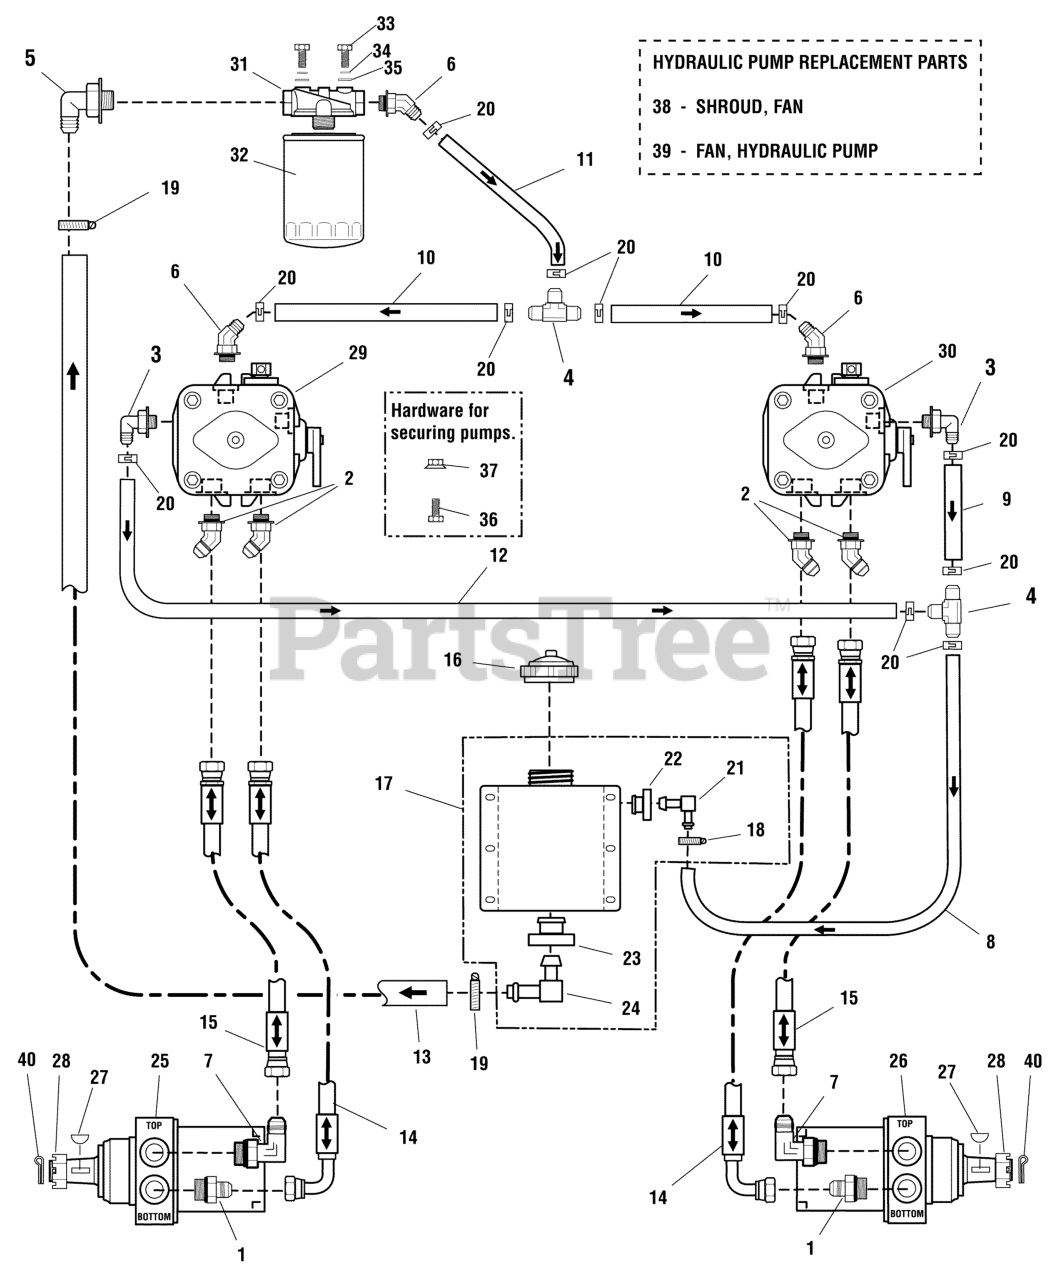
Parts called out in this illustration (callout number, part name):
1	ADAPTER, HYDRAULIC
2	FITTING, #8 JIC - #8 O-RING 45DEG.
3	ADAPTER, 90 DEG. 9/16 - 3/8 BARB
4	FITTING, TEE, 1/2" HOSE
5	ADAPTER, 90 DEG. 9/16 - 5/8 BARB
6	ADAPTER, 45, 9/16 - 3/8 BARB
7	FITTING, #10 ORING-#8 JIC, 90D
8	HOSE, 3/8" PUSH-LOCK, 16.00"
9	HOSE, 3/8" PUSH-LOCK, 6.50"
10	HOSE, 3/8" PUSH-LOCK, 6.00"
11	HOSE, 3/8" PUSH-LOCK, 8.00"
12	HOSE, 3/8" PUSH-LOCK, 23.00"
13	HOSE, 5/8" PUSH-LOCK, 25.00"
14	HOSE ASSEMBLY, (26.50)
15	HOSE ASSEMBLY, 22.50"
16	CAP, HYDRAULIC
17	TANK, HYDRAULIC, ASSEMBLY
18	CLAMP, #4 HOSE, STAINLESS
19	CLAMP, #10 HOSE, STAINLESS
20	CLAMP, HOSE
21	FITTING, ELBOW, 3/8"
22	BUSHING-FUEL TANK RED RUBBER
23	GROMMET
24	FITTING, ELBOW, 5/8"
27	KEY
28	NUT, CASTLE, 1-20
29	PUMP, HYD, 12CC - LH, PK-3HBQ-FV1F-XXXX
30	PUMP, HYD, 12CC - RH, PK-3KBQ-FV1F-XXXX
31	FILTER HEAD, HYDRAULIC
32	FILTER, OIL
33	BOLT, 1/4"-20 X 3/4" GD5 YZ
34	WASHER, 1/4 SAE
35	WASHER, 1/4 LOCK
36	BOLT, 3/8-16 X 1-1/4" GD5 CZ
37	NUT, 3/8-16 HEX SERRATED FLANGE
38	SHROUD, FAN
39	FAN, HYD. PUMP
40	PIN, COTTER, 1/8" X 2"
